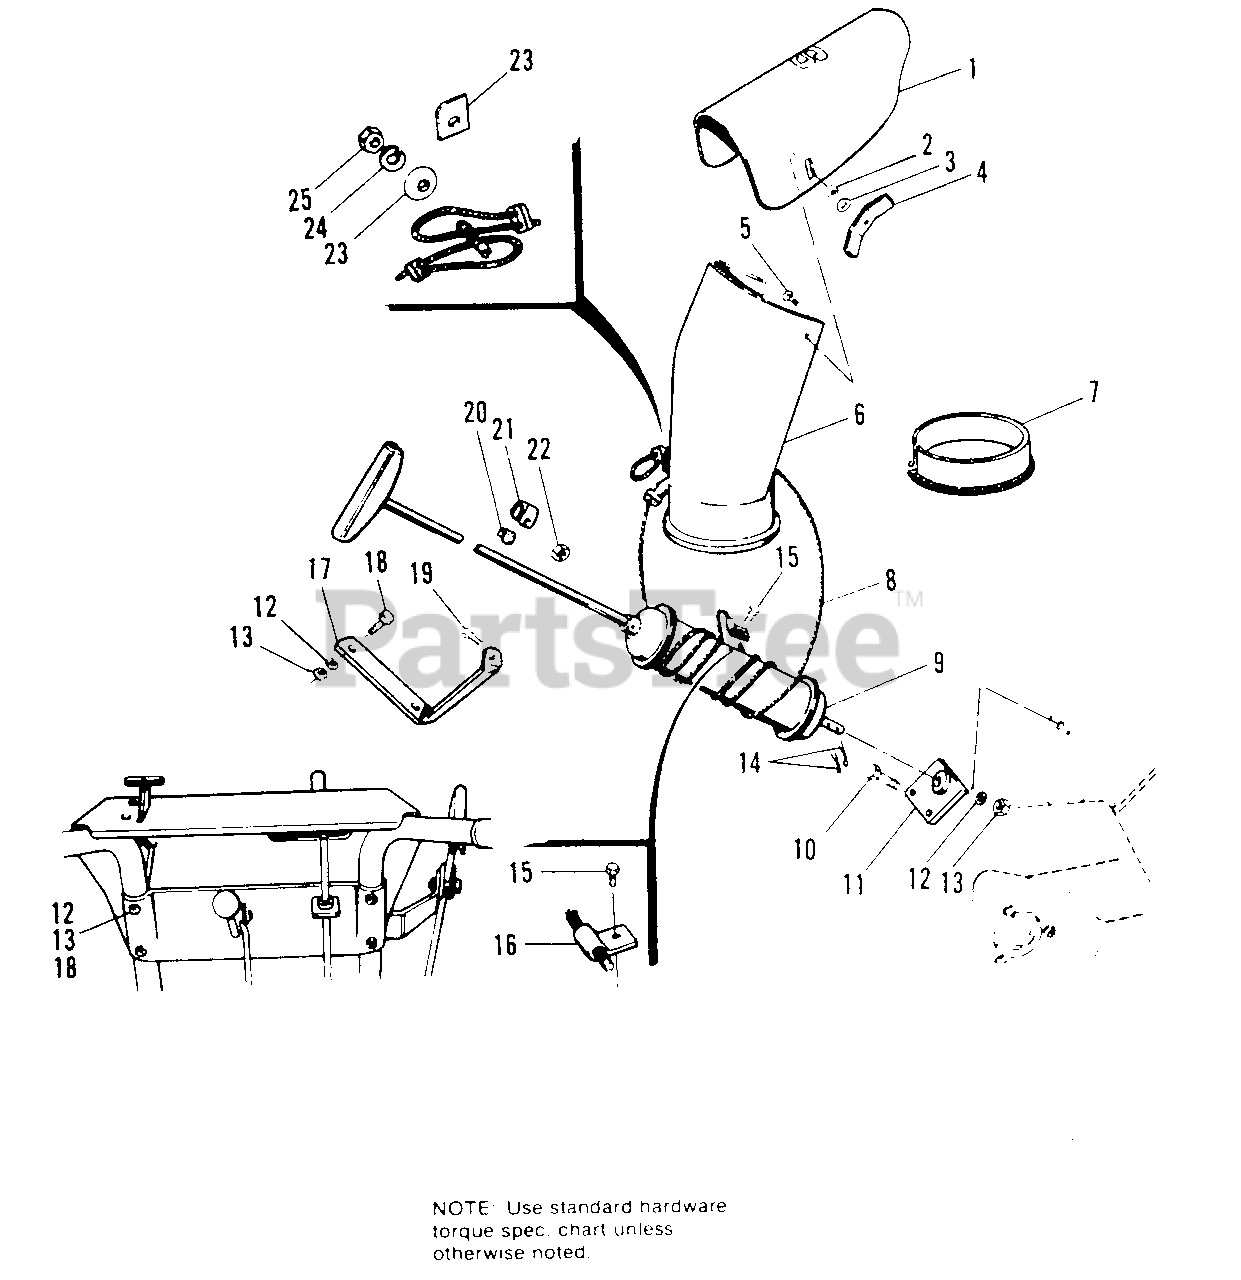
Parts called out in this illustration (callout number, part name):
1	EXTENSION, Spout
2	LOCKWASHER, Pyramdial Type, 3/8
3	WASHER, Plain, 3/8
4	NUT, Wing, 5/16-18
5	BOLT, Carriage, 5/16-18 x 3/4
6	SPOUT ASSY.
7	LINER (990430 & 990560 Only)
8	CABLE ASSY. (990430 & 990560 Only)
8	CORD, Spout
9	TUBE ASSY., Spout Control
10	CAPSCREW, Hex Hd., 1/4-20 x 5/8
12	LOCKWASHER, 1/4
13	NUT, Hex, Full, 1/4-20
14	PIN, Cotter, 1/8 x 3/4
15	SCREW, Taptite, 1/4-20 x 3/8
17	SUPPORT, Spout Adjusting Rod
18	CAPSCREW, Hex Hd., 1/4-20 x 1-3/4
19	CAPSCREW, Hex Hd., 5/16-18 x 1-1/4
21	GUIDE, Rod (990430 & 990560 Only)
21	GUIDE, Rod (990372 Only)
22	LOCKNUT, Hex, 5/16-18
23	WASHER, Cup (990430 & 990560 Only)
23	PLATE, Friction (990372 Only)
24	LOCKWASHER, 5/16
25	NUT, Hex, Full, 5/16-18
